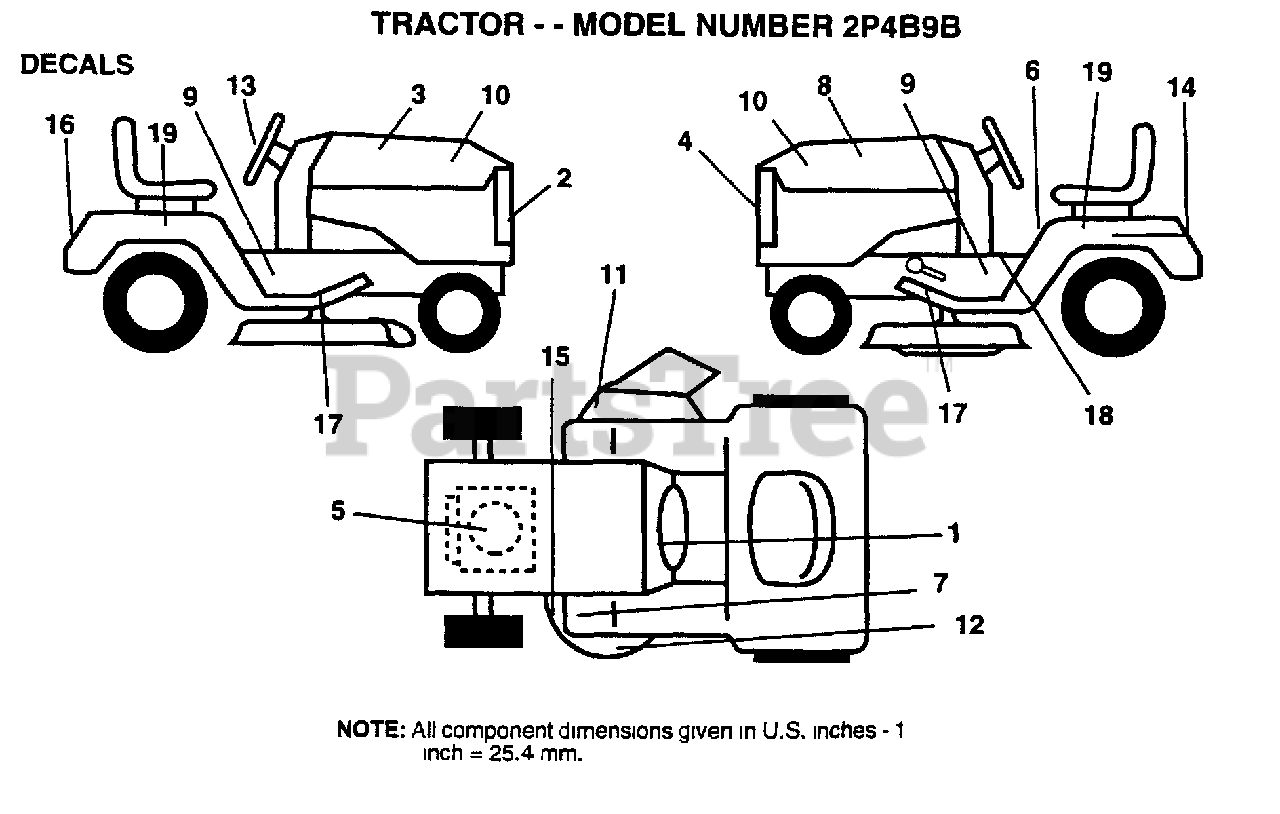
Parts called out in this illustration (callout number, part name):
1	DECAL.DASH.INSTR.
2	GRILL DECAL
3	DECAL HOOD RH RLY
5	DECAL B&S 18 HP OPLLN/IC
6	DECAL CAUTION
7	DECAL T
8	DECAL DANGER E/S
9	CHASSIS DECAL
10	DECAL.HOOD.INSERT
11	"DECAL, WARNING"
13	"DECAL,STR WHL"
14	DECAL.BATRY.3-3908
15	DECAL
16	FENDER DECAL
17	"PAD,FOOTREST"
18	DECAL BRAK PARK
19	DECAL.FEND.QUICKS
